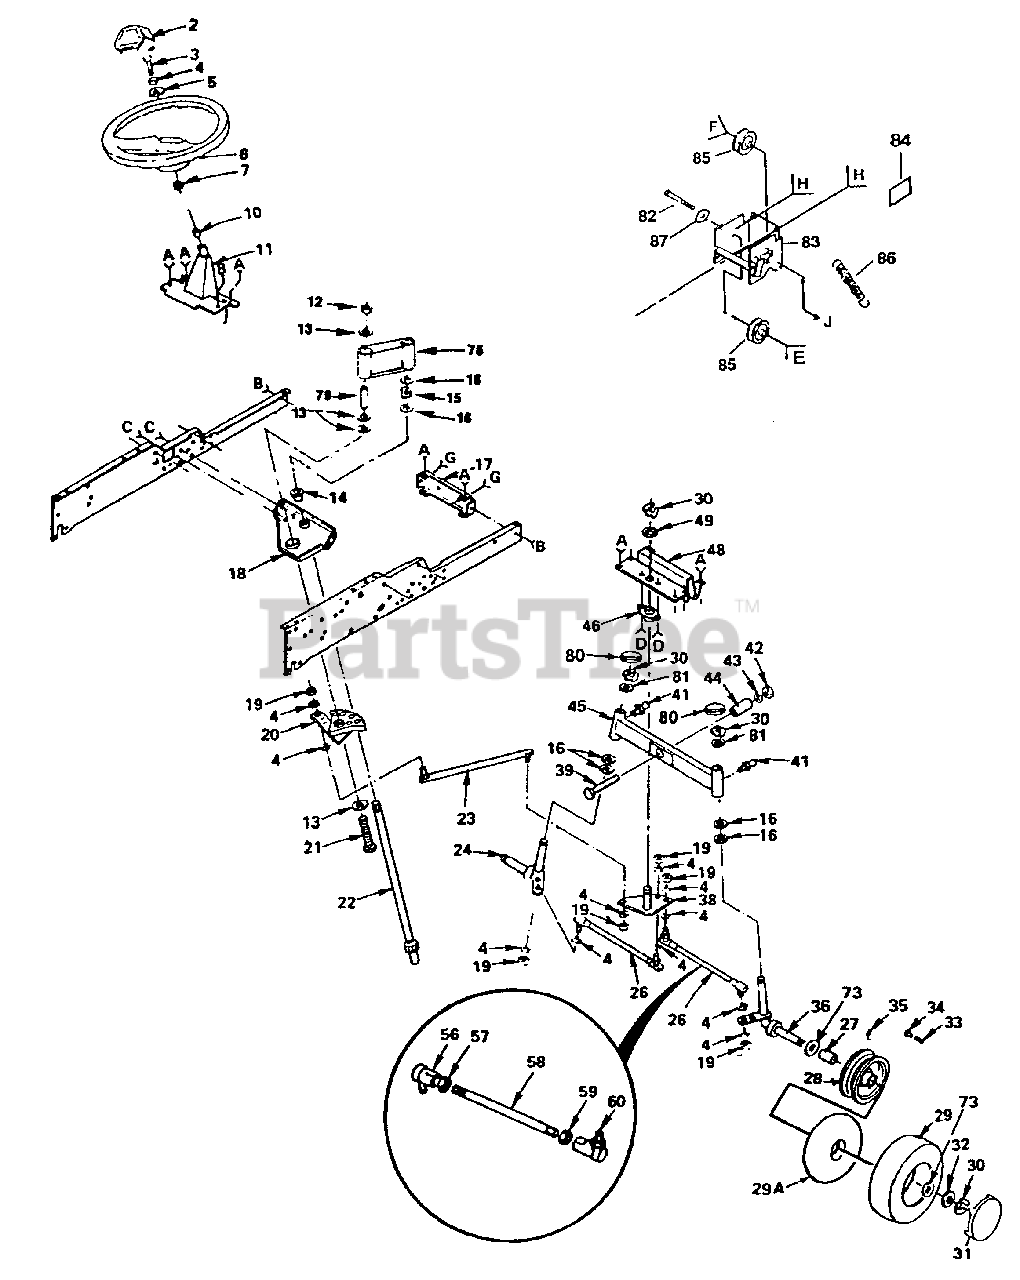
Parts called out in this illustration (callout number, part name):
2	Insert - Steering Wheel
3	Bolt - Hex 3/8-16 x 1 Gr. 5
4	Washer - Lock 3/8
5	Washer 13/32 x 2 - 3/8 x 8 Ga.
6	Wheel, Steering
7	Adapter, Steering
11	Support Assembly, Steering
12	Nut, Lock 1/2-13
13	Washer 17/32 x 1-5/8 x 10 Ga.
14	Bearing, Flanged
16	Bearing, Thrust
17	Bracket, Frame Front
18	Bracket, Support, Steering
19	Nut, Hex 3/8-24
20	Sector Assembly
21	Bolt - Hex 1/2-13 x 5 Gr. 5
22	Shaft, Steering
23	Link, Drag
24	Spindle, L.H.
26	Rod, Tie
28	Rim Assembly - 8" Front
29	Tire
29A	Tube
31	Cover, Wheel
32	Washer 25/32 x 1-5/8 x 16 Ga.
33	Cap, Valve
34	Stem, Valve
35	Fitting, Grease
36	Spindle, R.H.
38	Bellcrank Assembly
39	Bolt, Hex 5/8 -11 x 2 - 3/4 Gr. 5
41	Fitting, Grease
42	Nut, Hex 5/8 -11
43	Washer, Lock 5/8
44	Tube, Pivot, Axle
45	Axle Assembly, Front
46	Bushing, Bellcrank
48	Bracket, Axle
56	Joint-Tie Rod - L.H Thread
57	Nut Hex Jam 3/8 - 24 L.H.
59	Nut Hex Jam 3/8 - 24
60	Joint, Tie Rod - R.H. Thread
73	Washer, 25/32 x 1-1/4 x 16 Ga.
76	Collar Weld Ass'y.
80	Dust Cap Cover
81	Washer 25/32 x 1 - 5/8 x 16 Ga.
82	Bolt-Hex 3/8 - 16 x 2
83	Brkt. Idler
84	Decal, Adjustment
85	Pulley, Idler
87	Washer 13/32 x 2 - 3/8 x 8 Ga.
